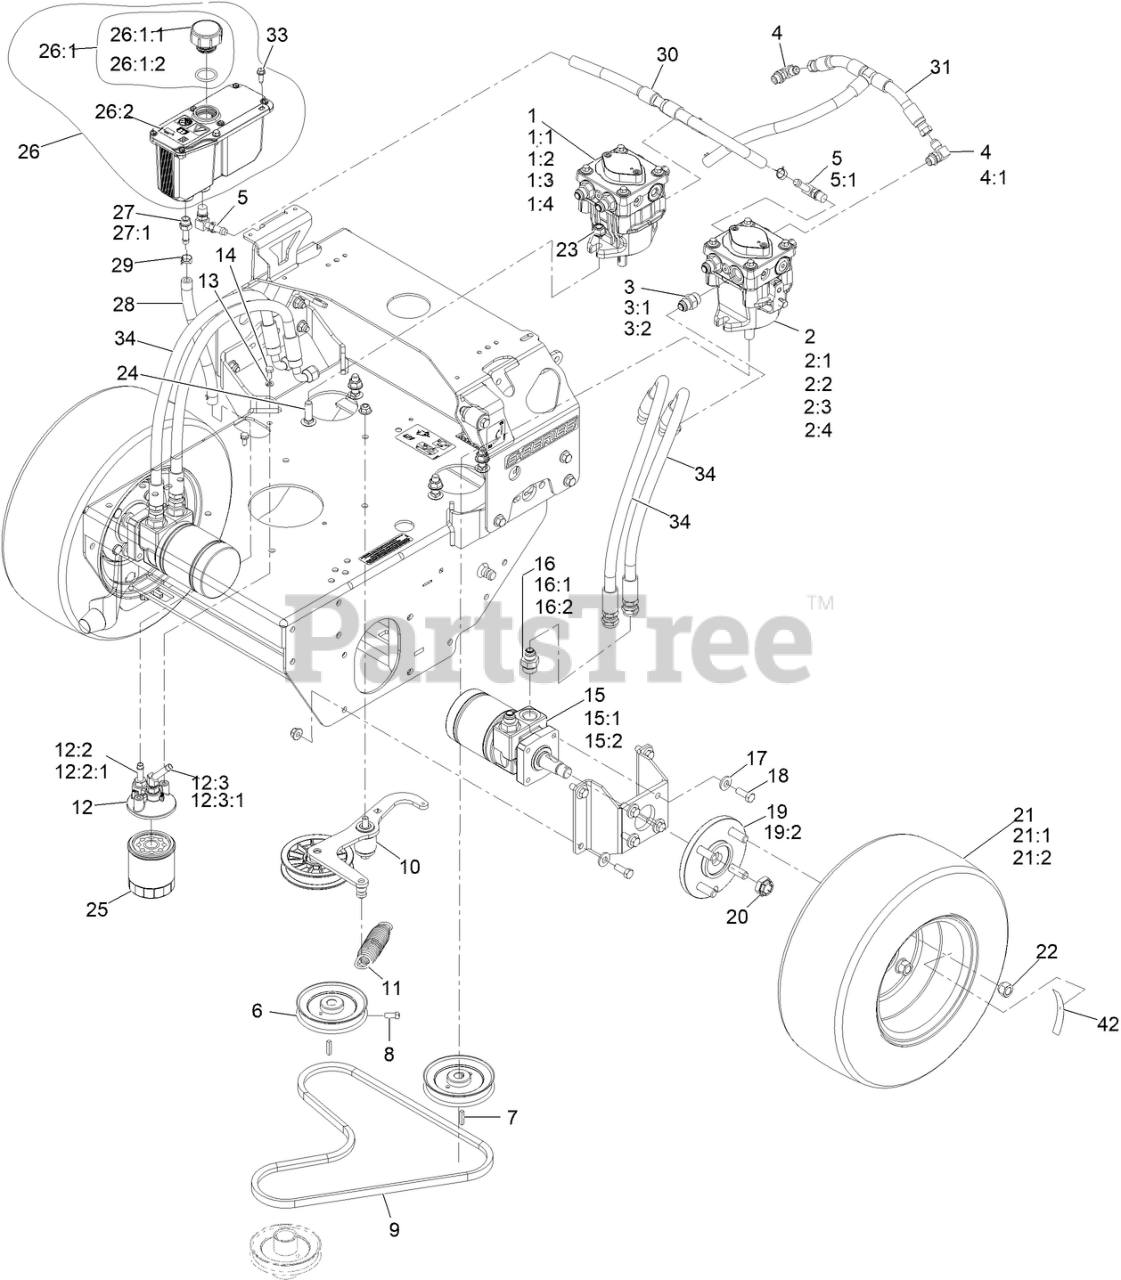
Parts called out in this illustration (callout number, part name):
1	RH HYD PUMP ASM
1:1	INPUT SHAFT KIT
1:2	BEARING-THRUST
1:3	CYLINDER BLOCK KIT
1:4	SEAL OVERHAUL KIT
2	LH HYD PUMP ASM
2:1	INPUT SHAFT KIT
2:2	BEARING-THRUST
2:3	CYLINDER BLOCK KIT
2:4	SEAL OVERHAUL KIT
3	FITTING-STRAIGHT
4	FITTING-ELBOW, 90 DEG
4:1	O-RING
5	FITTING-ELBOW, 90
5:1	O-RING
6	SHEAVE ASM
8	SCREW-SET, SQH
9	BELT
10	ASM, PUMP IDLER
11	SPRING-EXTENSION
12	ASM, FILTER HEAD
12:2	ADAPTER-STRAIGHT
12:2:1	O-RING
12:3	FITTING-BARBED, 45 DEG
12:3:1	O-RING
13	WASHER-LOCK
14	SCREW-HH
15	HYD MOTOR ASM
15:1	SEAL KIT
15:2	BEARING AND SEAL KIT
16	FITTING-STRAIGHT
16:1	O-RING
17	WASHER-BELLEVILLE
18	SCREW-HH
19	WHEEL HUB ASM
19:2	STUD-WHEEL
20	NUT-LOCK
21	ASM, WHEEL AND TIRE 16X6.50X8
21:2	16/650X8 4-Ply Grassmaster Tl
22	NUT-LUG
23	NUT-HF, NI
24	BOLT-CARR
25	FILTER-25 MICRON, BI-DIRECTIONAL
26:1	Reservoir-HYD
26:1:1	Cap-Reservoir, HYD
26:2	DECAL-WARNING
27	ADAPTER-STRAIGHT
27:1	O-RING
28	HOSE-CHARGE
29	CLAMP-HOSE
30	HOSE-CASE DRAIN
31	HOSE-CHARGE
33	SCREW-HWH, THREAD ROLL
34	HYD HOSE ASM
42	DECAL-TORQUE WHEEL LUG-HU
